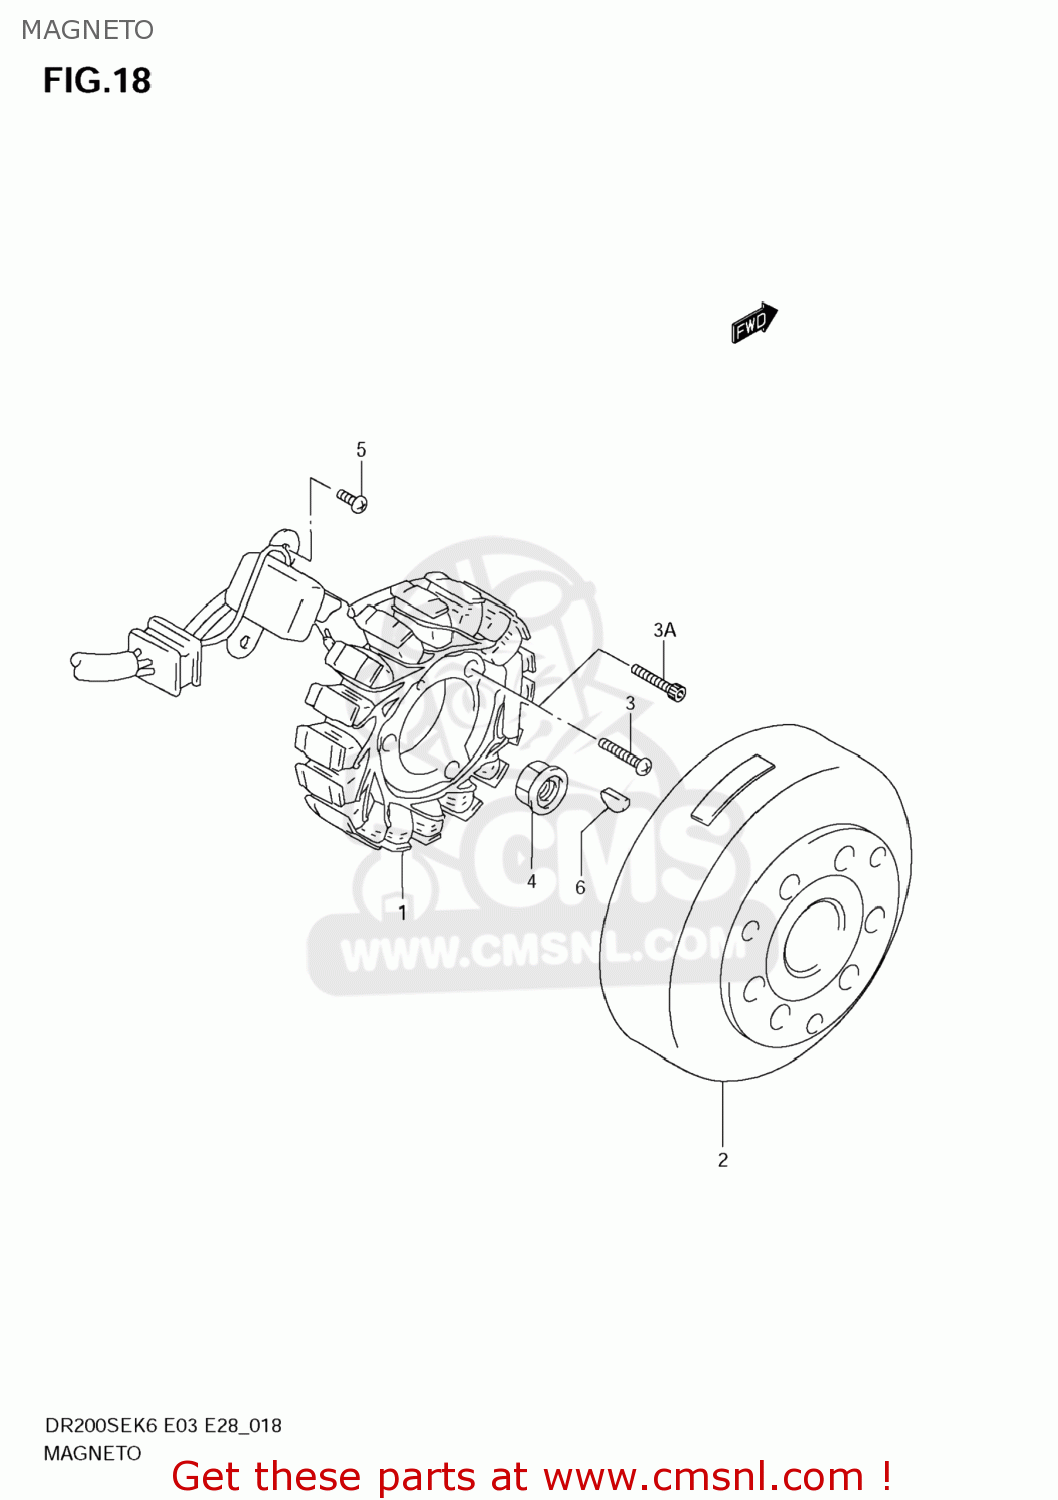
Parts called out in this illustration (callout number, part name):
1	STARTER ASSY
2	ROTOR ASSY
3	SCREW
3A	BOLT
4	NUT,MAGNETO ROTOR
5	SCREW
6	KEY
